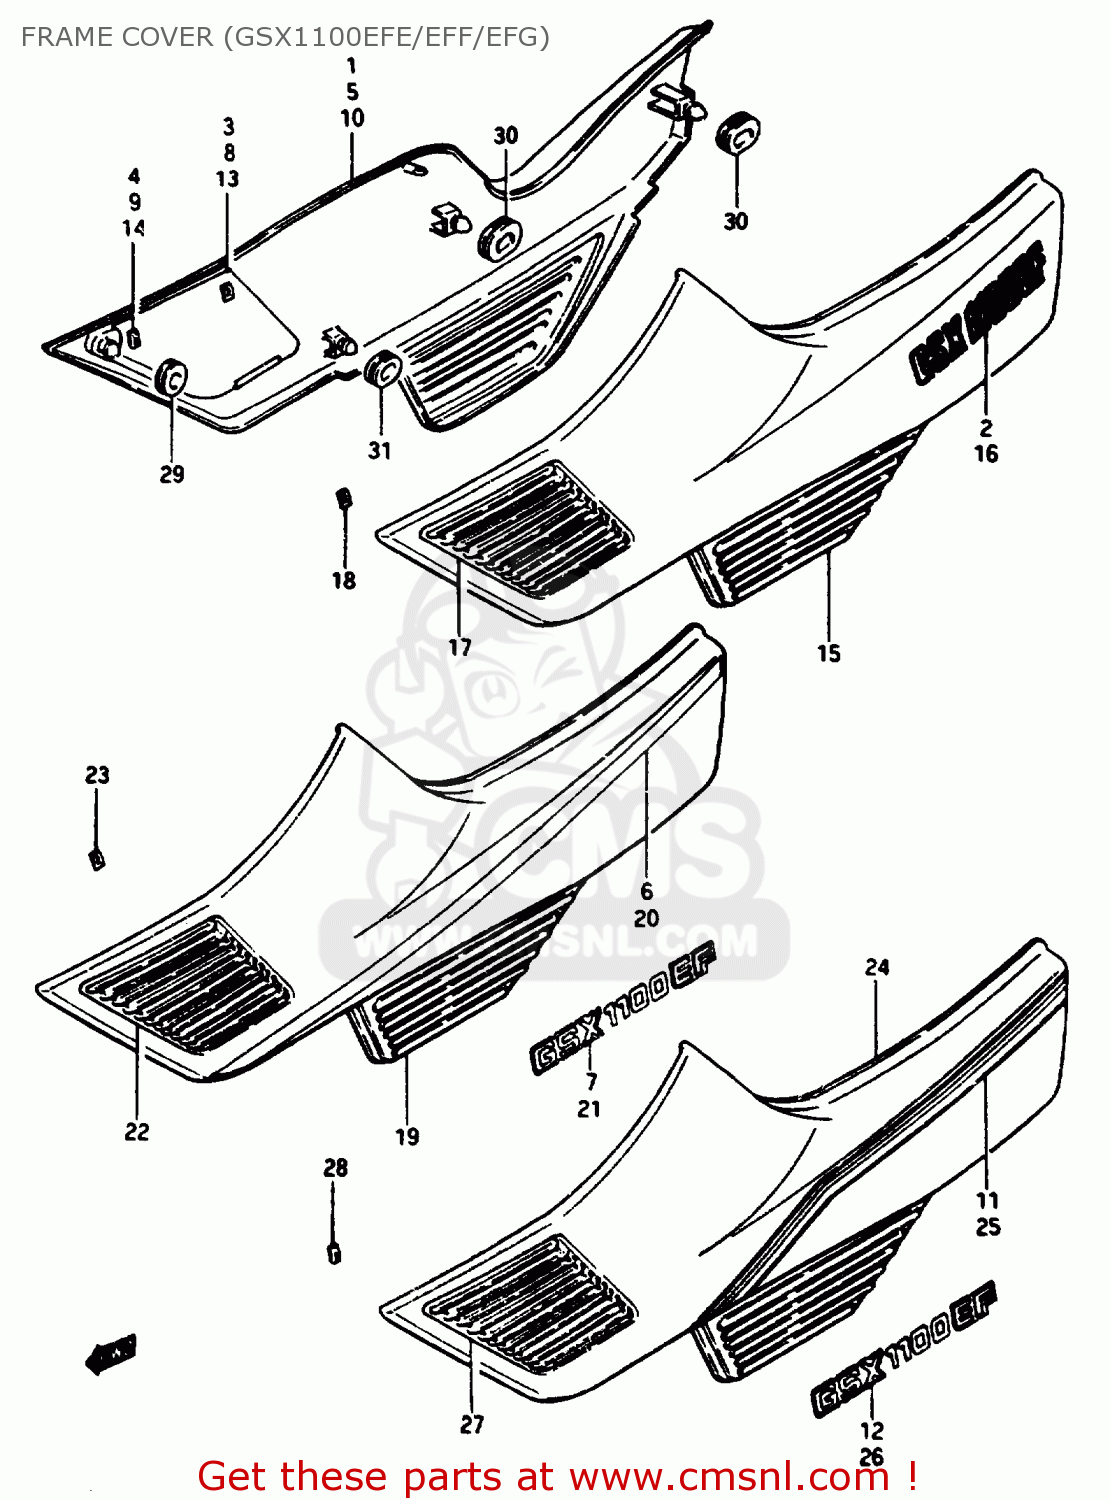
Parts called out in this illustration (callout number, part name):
1	COVER, FRAME RH (RED)
2	EMBLEM
3	COVER,FRAME,RIGHT
4	NUT
5	COVER, FRAME RH
6	TAPE SET,FRAME COVER,RIGHT
7	EMBLEM
8	COVER,FRAME,RIGHT NO.1
9	NUT
10	COVER, FRAME RH
11	TAPE SET, FRAME COVER RH
12	EMBLEM
13	COVER,FRAME,RIGHT NO.1
14	NUT
15	COVER, FRAME LH (RED)
16	EMBLEM
17	COVER,FRAME,RIGHT NO.1
18	NUT
19	COVER, FRAME LH
20	TAPE SET,FRAME COVER,LEFT
21	EMBLEM
22	COVER,FRAME,RIGHT NO.1
23	NUT
24	COVER, FRAME LH
25	TAPE SET, FRAME COVER LH
26	EMBLEM
27	COVER,FRAME,RIGHT NO.1
28	NUT
29	CUSHION
30	CUSHION
31	CUSHION
